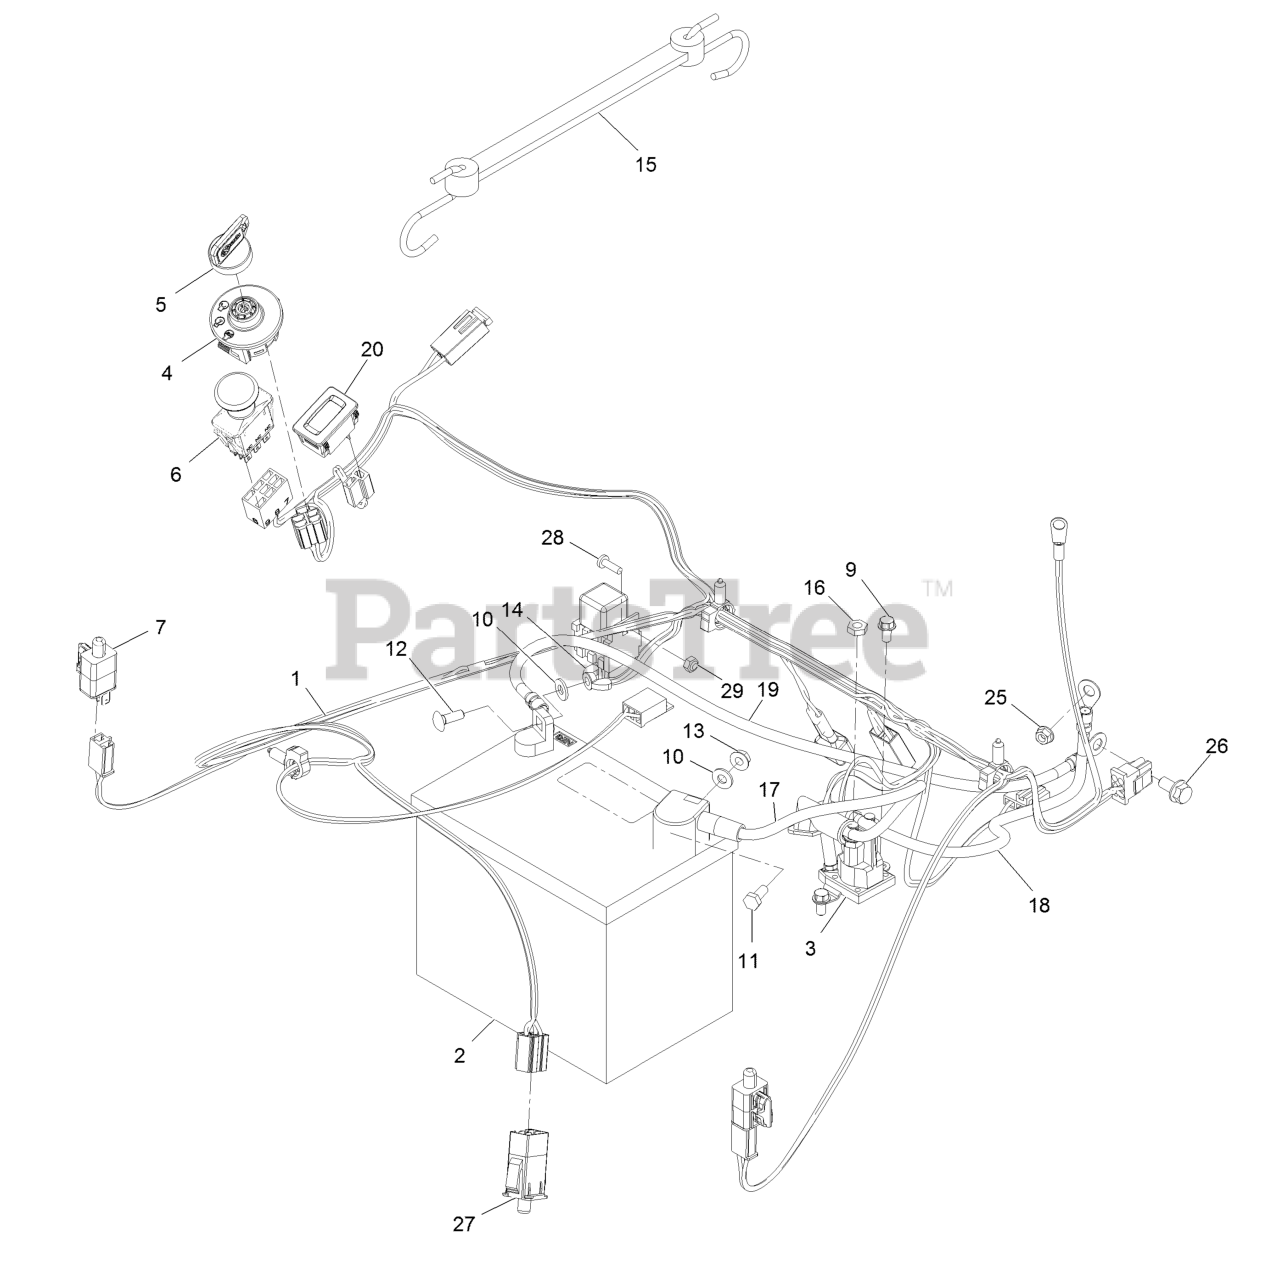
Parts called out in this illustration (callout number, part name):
1	Harness-Wire
2	Battery
3	Solenoid
4	Switch-Ignition
5	Key-Exmark Logo
6	Switch-PTO
9	Screw-HWH 1/4-20 X 1/2 Taptite
10	Washer-1/4 SAE
11	Screw-HH 1/4-20 X 5/8
12	Bolt-Carriage 1/4-20 X 3/4
13	Nut-Whizlock 1/4-20
14	Nut-Wing
15	Holddown-Battery
16	Nut-Jam 5/16-24
17	Cable-Battery, Red
18	Cable-Battery, Positive
19	Cable-Battery, Black
20	Hourmeter
25	Nut-Hex M6-1 Flg
26	Screw-HH Flg 5/16-18 X 5/8
27	Switch-Delta
28	Screw-PPH #10-24 X 5/8
29	Nut-Nyloc #10-24
